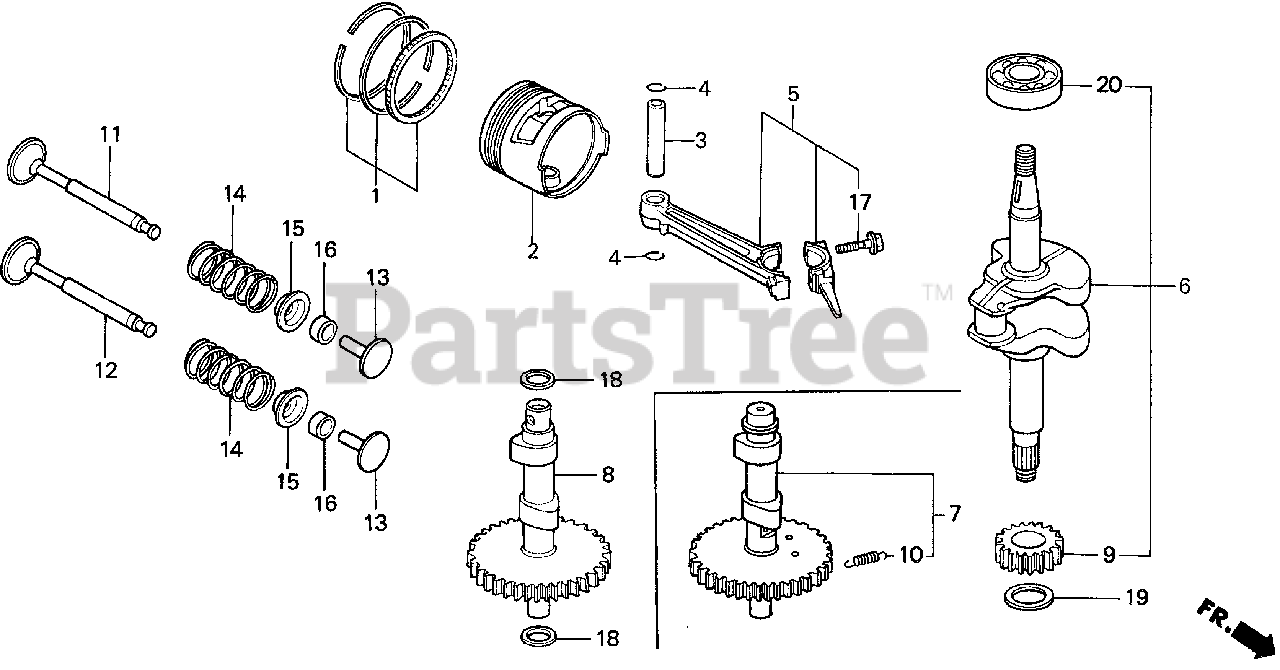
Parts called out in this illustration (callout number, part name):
1	RING SET, PISTON (STD)
1	RING SET, PISTON (OVER SIZE) (0.25)
1	RING SET, PISTON (OVER SIZE)
1	RING SET, PISTON (0.75)
2	PISTON (STD)
2	PISTON (OVER SIZE) (0.25)
2	PISTON (OVER SIZE) (0.50)
2	PISTON (OVER SIZE) (0.75)
3	PIN, PISTON
4	CLIP, PISTON PIN (10MM)
5	ROD ASSY., CONNECTING (UNDER SIZE) Use up to Engine SN 1214439.
5	ROD ASSY., CONNECTING (STD)
6	CRANKSHAFT
8	CAMSHAFT
9	GEAR, TIMING
11	VALVE, IN.
12	VALVE, EX.
13	LIFTER, VALVE
14	SPRING, VALVE
15	RETAINER, VALVE SPRING
16	ADJUSTER, TAPPET CLEARANCE (3.15)
16	ADJUSTER, TAPPET CLEARANCE (3.25)
16	ADJUSTER, TAPPET CLEARANCE (3.34)
16	ADJUSTER, TAPPET CLEARANCE (3.43)
16	ADJUSTER, TAPPET CLEARANCE (3.52)
16	ADJUSTER, TAPPET CLEARANCE (3.61)
16	ADJUSTER, TAPPET CLEARANCE (3.72)
16	ADJUSTER, TAPPET CLEARANCE (3.82)
17	BOLT, CONNECTING ROD
18	WASHER (12MM)
19	WASHER, THRUST (20X1.00)
20	BEARING, RADIAL BALL (6203)
